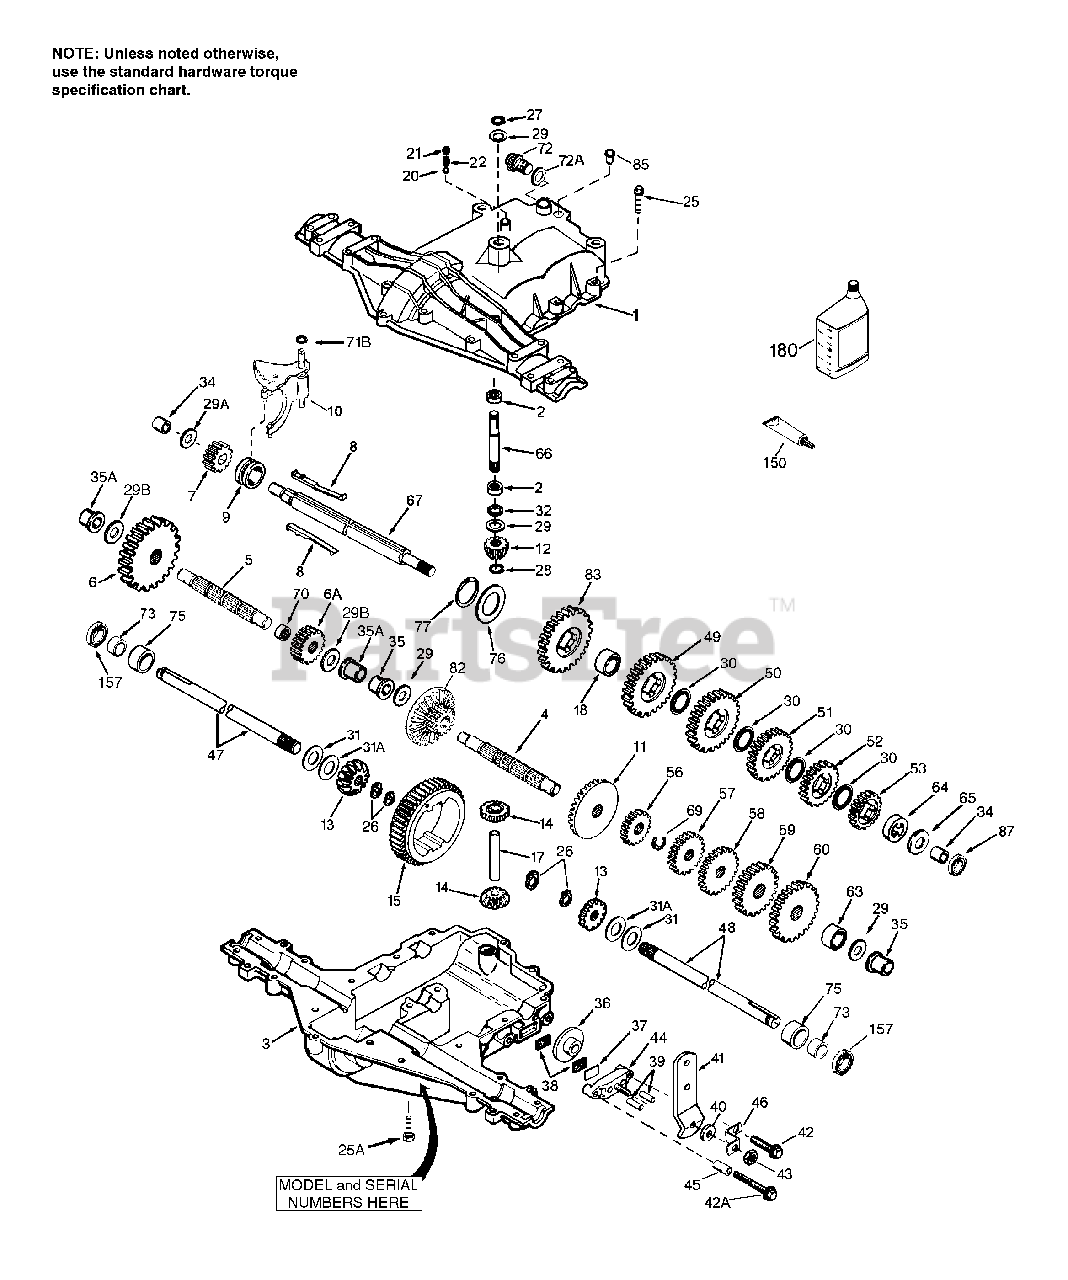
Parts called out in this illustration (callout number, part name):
1	Transaxle Cover
2	Needle Bearing 5/8" ID
3	Transaxle Case
4	Countershaft
5	Output Shaft
6	Spur Gear (38 teeth)
6A	Spur Gear (15 teeth-steel)
7	Spur Gear (11 teeth-steel)
8	Shift Key
9	Shift Collar
10	Shift Rod & Fork
11	Bevel Gear (30 teeth)
12	Input Bevel Pinion (13 teeth)
13	Bevel Gear (16 teeth-steel) (Incl. 14)
14	Bevel Gear (16 teeth-steel) (Incl. 13)
15	Ring Gear (43 teeth)
17	Drive Pin
18	Spacer
20	Ball 5/16" dia.
21	Set Screw 3/8-16 x 3/8"
22	Spring
25	Screw 1/4-20 x 1-1/4"
25A	Screw 1/4-20 X 1-3/8"
26	Retaining Ring (pkg of 2)
27	Retaining Ring
28	Retaining Ring
29	Washer
29A	Washer
29B	Thrust Washer
30	Washer
31	Washer (.056 wide) (USE AS NEEDED)
31A	Flat Washer (.062 wide) (USE AS NEEDED)
32	Oil Seal 5/8"
34	Bushing
35	Flanged Bushing
35A	Flanged Bushing 3/4"
36	Brake Disk
37	Brake Pad Plate
38	Brake Pad (pkg of 2)
39	Dowel Pin
40	Washer
41	Brake Lever
42	Screw 1/4-20 x 1-1/4"
42A	Screw 1/4-20 x 2-1/4"
43	Locknut 5/16-24
44	Brake Pad Holder
45	Spacer
46	Brake Lever Bracket
47	Axle (12-7/32" long)
48	Axle (16-13/16" long)
49	Spur Gear (29 teeth-steel)
50	Spur Gear (23 teeth-steel)
51	Spur Gear (19 teeth-steel)
52	Spur Gear (16 teeth-steel)
53	Spur Gear (15 teeth-steel)
56	Spur Gear (11 teeth-steel)
57	Spur Gear (17 teeth-steel)
58	Spur Gear (21 teeth-steel)
59	Spur Gear (24 teeth-steel)
60	Spur Gear (25 teeth)
63	Countershaft Spacer 1-1/8" x 3/8"
64	Brake Shaft Spacer 1-3/8" X 3/8"
65	Washer
66	Input Shaft
67	Shifter & Brake Shaft
69	Retaining Ring
70	Spacer
71B	"O" Ring
72	Threaded Plug 9/16-18
72A	"O" Ring
73	Needle Bearing 3/4"
75	Sleeve .999 ID
76	Washer
77	Inverted Retaining Ring
82	Bevel & Spur Gear (30 & 13 teeth)
83	Spur Gear (27 teeth)
85	Oil Fill Plug
87	Oil Seal 9/16"
150	Liquid Gasket RTV Silicone
157	Oil Seal 3/4"
180	Gear Oil 80W90
